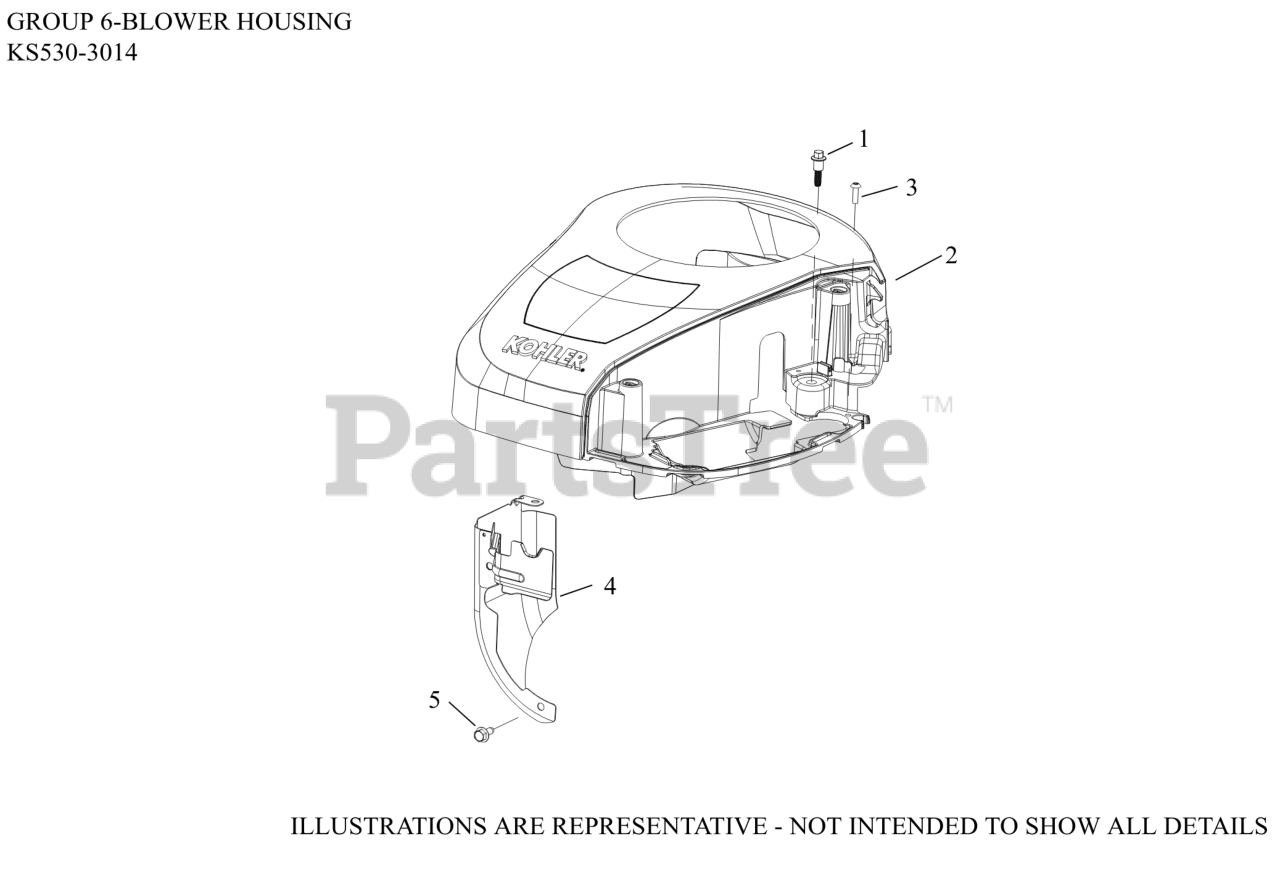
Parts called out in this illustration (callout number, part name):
1	SCREW, SHD THD FRM M6X1X26
2	KIT, BLOWER HOUSING
3	SCREW, HI-LOW
4	BAFFLE, BARREL ASSY
5	SCREW, THREAD FORMING
